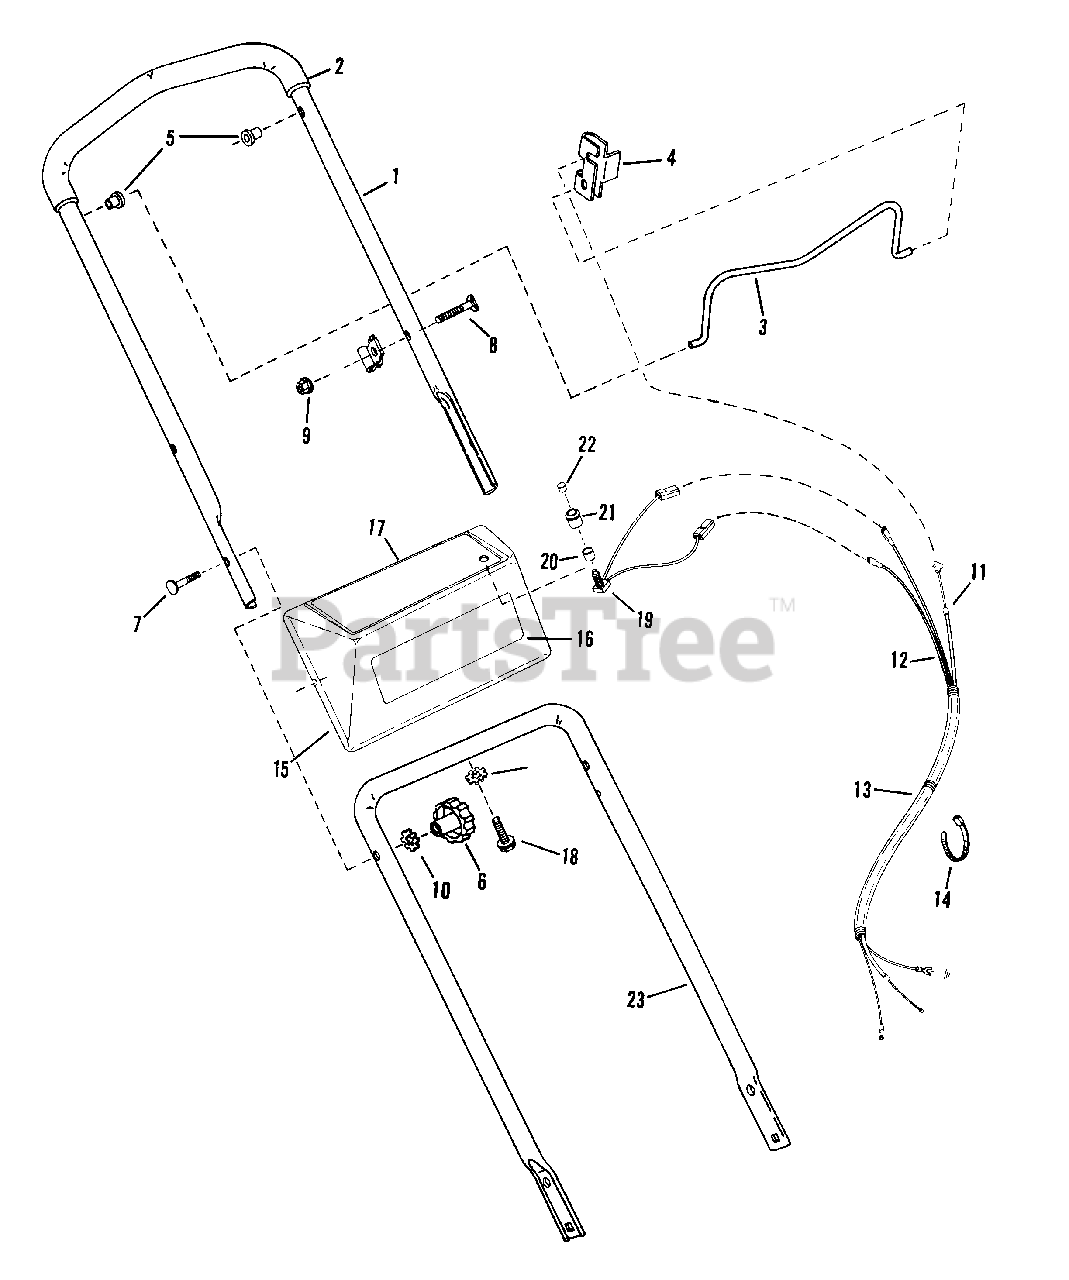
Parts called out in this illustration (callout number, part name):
1	HANDLE, Upper
2	GRIP, Foam
3	BAIL, Throttle
4	CLIP, Throttle
5	BUSHING, Bail
6	KNOB, 5/16-18 Plastic
7	BOLT, 5/16-18 x 2" Curved Head
8	BOLT, 1/4-20 x 1-1/2" Curved Head
9	NUT, 1/4-20 Hex Flange Lock
10	WASHER, 5/16 Int./Ext. Tooth Lock
11	ASSEMBLY, Throttle Cable
12	HARNESS, Wire
13	SHEATH, Harness
14	TIE, Cable
15	ASSEMBLY, Panel/Label
16	LABEL, Model
17	LABEL, Instruction
18	SCREW, 5/16-18 x 5/8" Self-Tapping
20	SPACER, Switch
21	BEZEL, Switch
22	CAP, Switch
23	HANDLE, Lower
